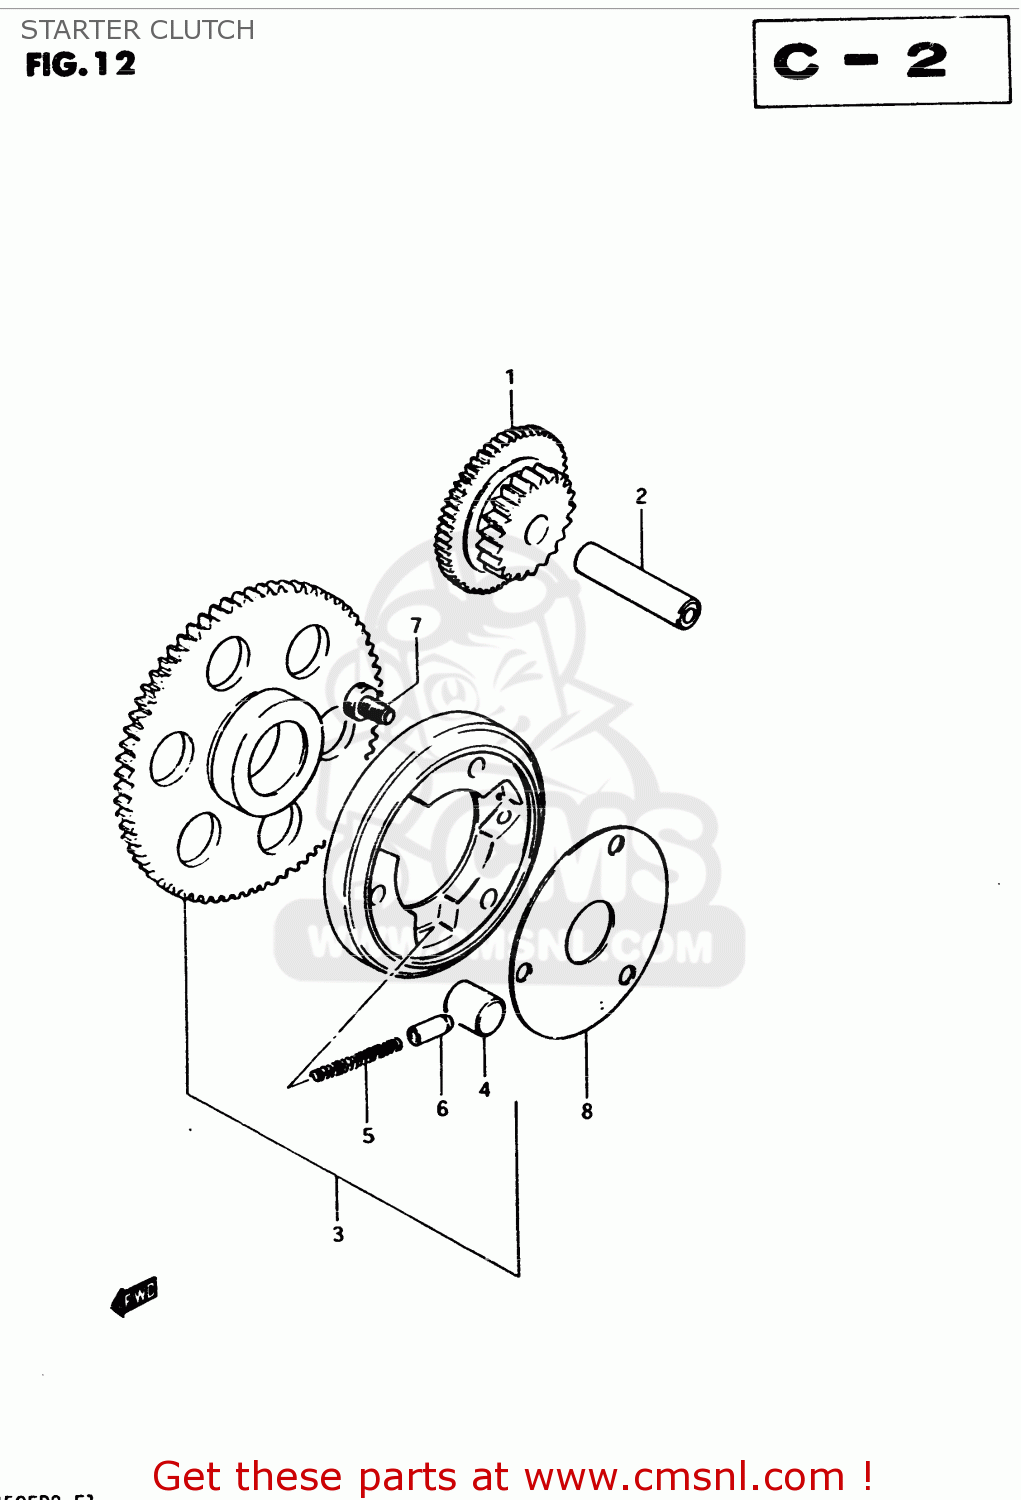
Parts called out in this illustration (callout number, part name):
1	GEAR,STARTER IDLE
2	PIN(7.4X13X56)
3	CLUTCH SET,STARTER
4	ROLLER(15X13)
5	SPRING
6	PIECE,PUSH
7	BOLT
8	SHIM,STARTER CLUTCH HUB
